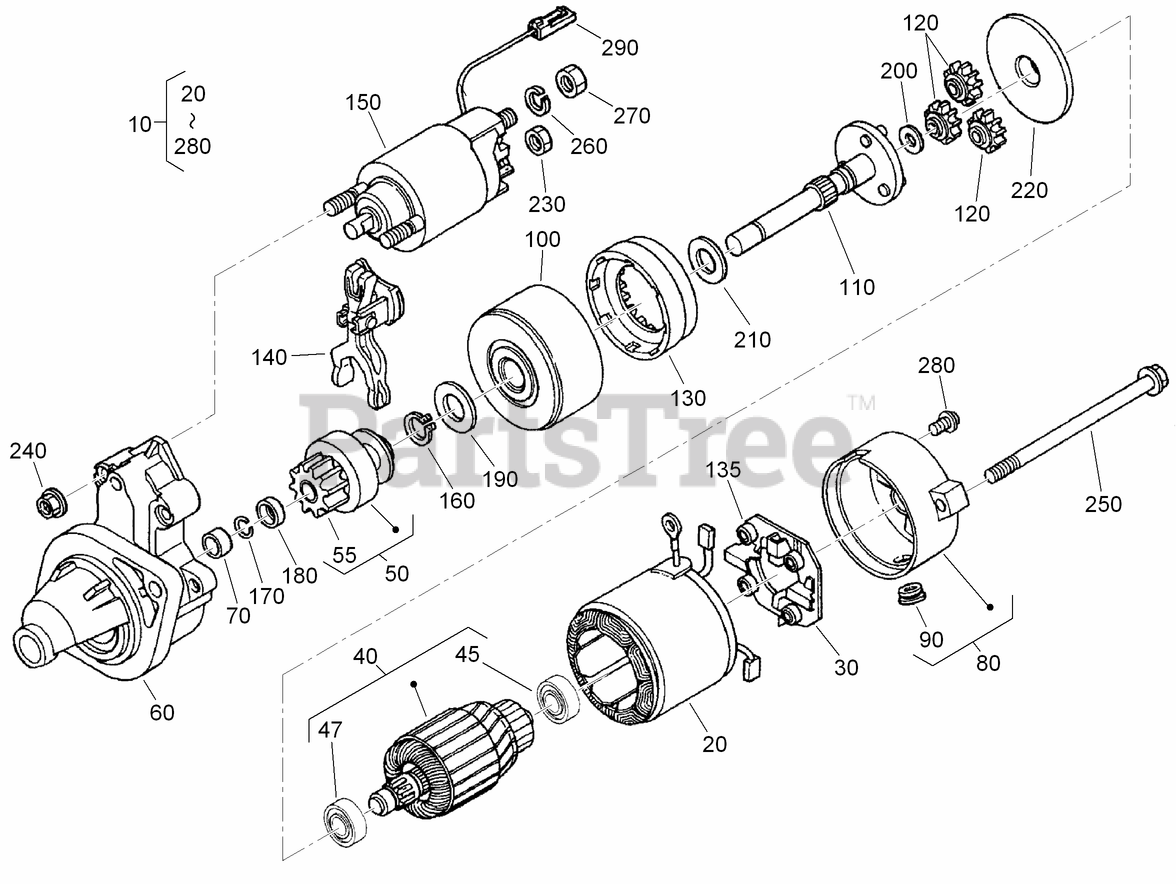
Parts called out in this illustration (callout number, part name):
10	STARTER ASM
20	STARTER YOKE ASM
30	HOLDER ASM
40	ARMATURE ASM
45	BEARING-BALL
47	BEARING-BALL
50	STARTER CLUTCH ASM
55	GEAR-PINION
60	STARTER HOUSING ASM
70	BEARING
80	FRAME ASM
100	BEARING ASM
110	STARTER SHAFT ASM
135	SPRING-BRUSH
150	MAGNETIC SWITCH ASM
160	RING-SNAP
170	RING-SNAP
180	COLLAR
190	WASHER-PLAIN
200	WASHER-PLAIN
210	WASHER-PLAIN
230	NUT-HEX
250	BOLT-THROUGH
260	WASHER-SPRING
270	NUT-HEX
290	WIRE-LEAD
